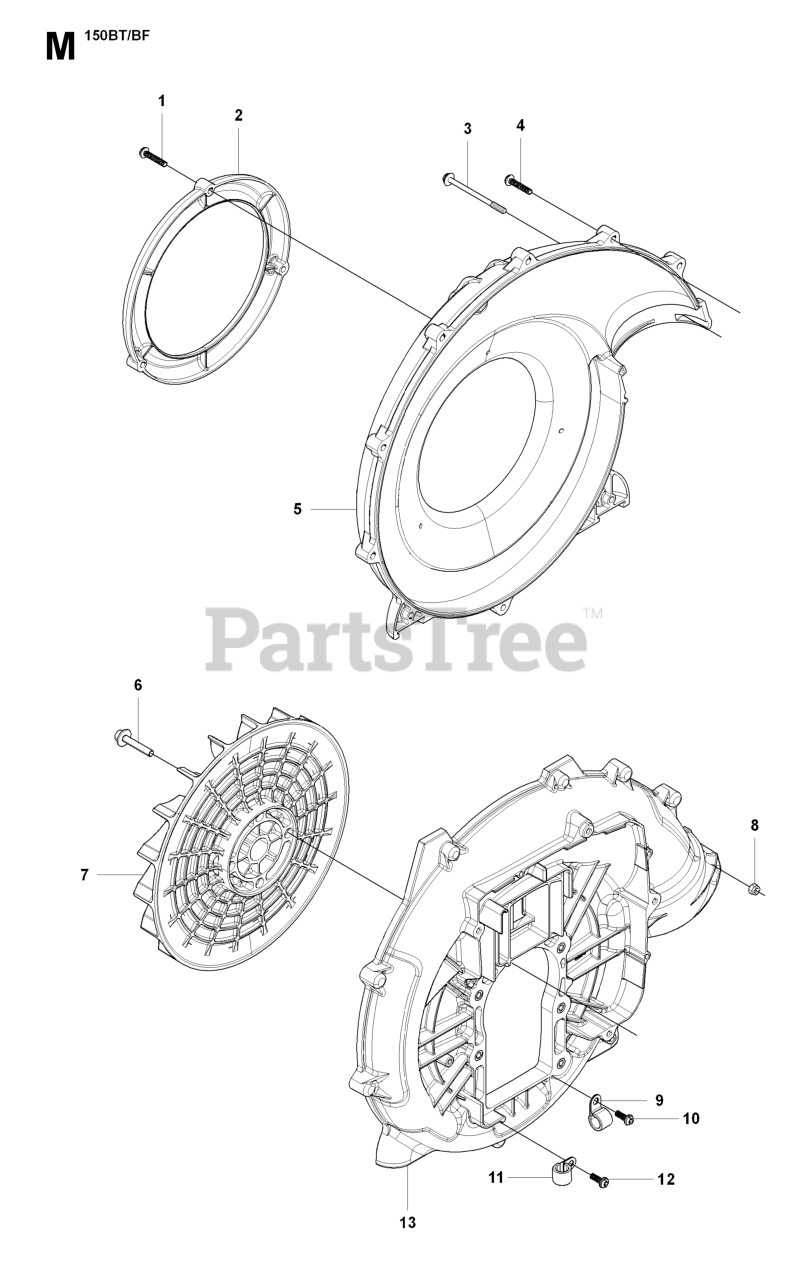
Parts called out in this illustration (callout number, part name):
1	SEAT.TH150.MS498.GRY.HUSQ.TEX
1	SCREW
2	PLATE.PNT.SEAT.SLIDE.3PT.EDIP
2	FUNNEL
3	PLATE.SUPPORT.DECK.LIFT.X431
4	PLATE.DECK.LIFT.X431
4	SCREW
5	SUPPORT.SEAT.RZ.HUSQ.ORANGE
5	VOLUTE COVER
6	SUPPORT REAR SEAT BLACK
6	RP_BOLT
7	SPRING.LATCH.SEAT.TEX
7	IMPELLER FAN
8	SPRING.COMPRESS.SEAT.TAPERED
8	NUT
9	SWITCH.SEAT.OPC.GRY.BUTTON/CAP
10	HANDLE.SLIDE.SEAT.TEX.BLACK
10	SCREW
11	SUPPORT.LEG.DECK.LIFT
11	RP_CLAMP
12	GROMMET.BUMPER
12	SCREW
13	U-CLIP 5/16-18 NUT RETAINER
13	FAN HOUSING VOLUTE
14	RP BOLT 5/16-18 X3/4 ZN/YEL GR
15	RHSNB 5/16-18 X 2-1/2 GR5 ZD
16	BOLT
18	BOLT, SHOULDER
19	SCREW.THDROL.5/16-18X3/4.TTY
20	BOLT.5/16HEX.WHS.HD
21	5/16-18 NYLOC FLANGE NUT
22	NUT 3/8-16 HEX FLG NYLOC ZD
23	RP WASHER 3/8 FLAT
24	WASHER.WINGED.3/8ID.1.5OD
